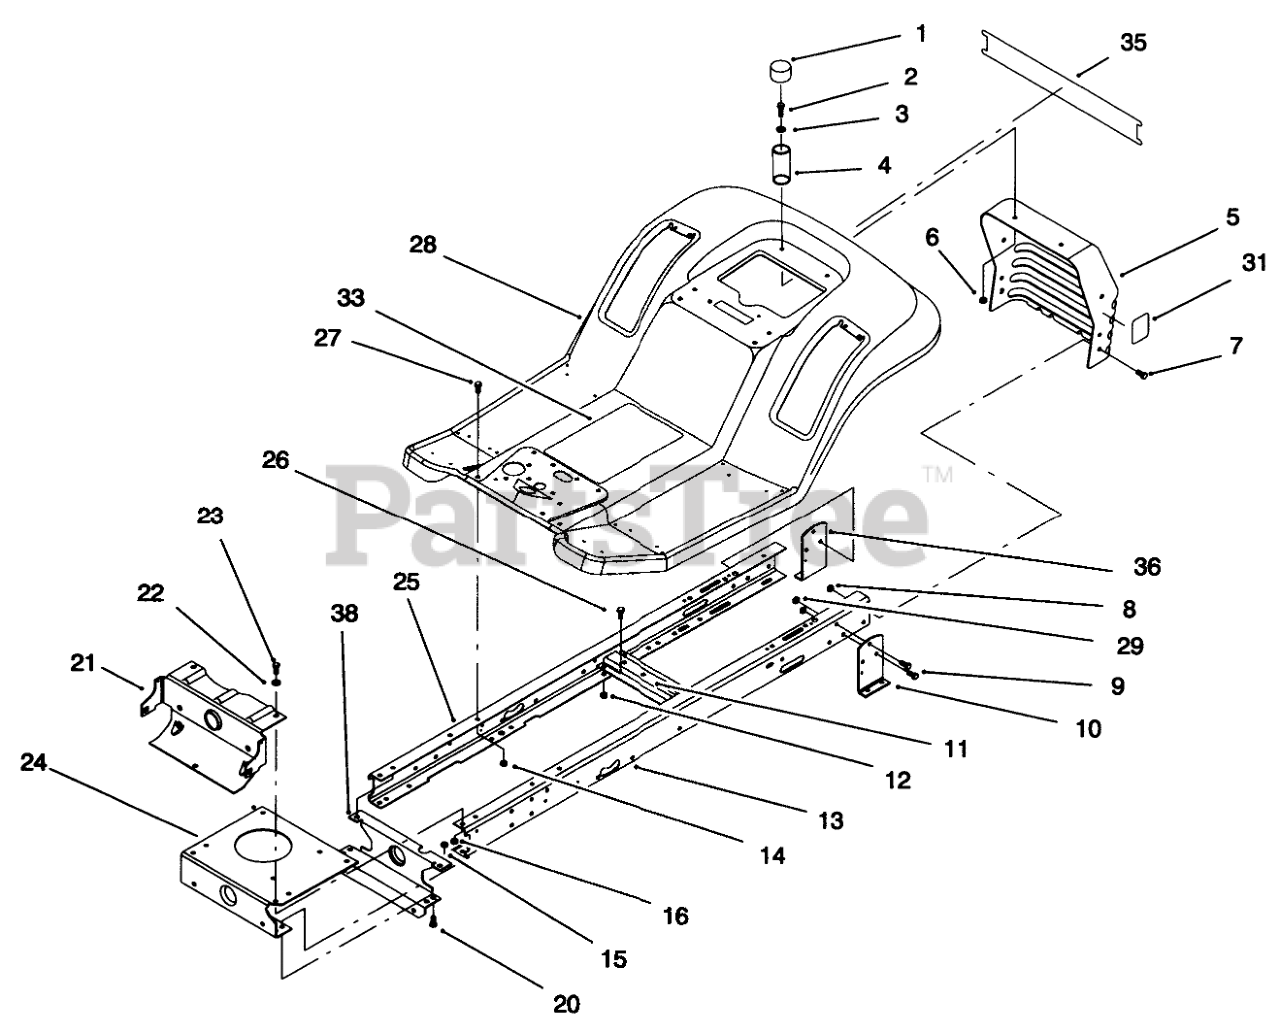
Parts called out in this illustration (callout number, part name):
1	CAP-PROTECTOR
2	SCREW-HH
3	WASHER-PLAIN
4	SPRING-COMPRESSION
5	Panel-Rear Hitch
6	NUT-LOCK, NI
7	SCREW-HH
8	NUT-LOCK, NI
9	SCREW-HH
10	Bracket-Trans. Mtg. L.H.
11	Bracket-Idle Pivot
12	NUT-LOCK, NI
13	Frame-Rail L.H.
14	NUT-LOCK, NI
15	NUT-LOCK, NI
16	NUT-LOCK, NI
20	SCREW-HH
21	Support-Front Axle
22	WASHER-PLAIN
23	SCREW-HH
24	Plate-Engine Mount
25	Frame-Rail R.H.
26	SCREW-HH
27	SCREW-HH
28	Body-Rear
29	NUT-LOCK, NI
31	DECAL - DUMP VALVE
33	DECAL-INSTRUCTION
35	DECAL-REAR BODY 1644 HXL
36	Bracket-Trans. Mtg. R.H.
38	Support-Rear
